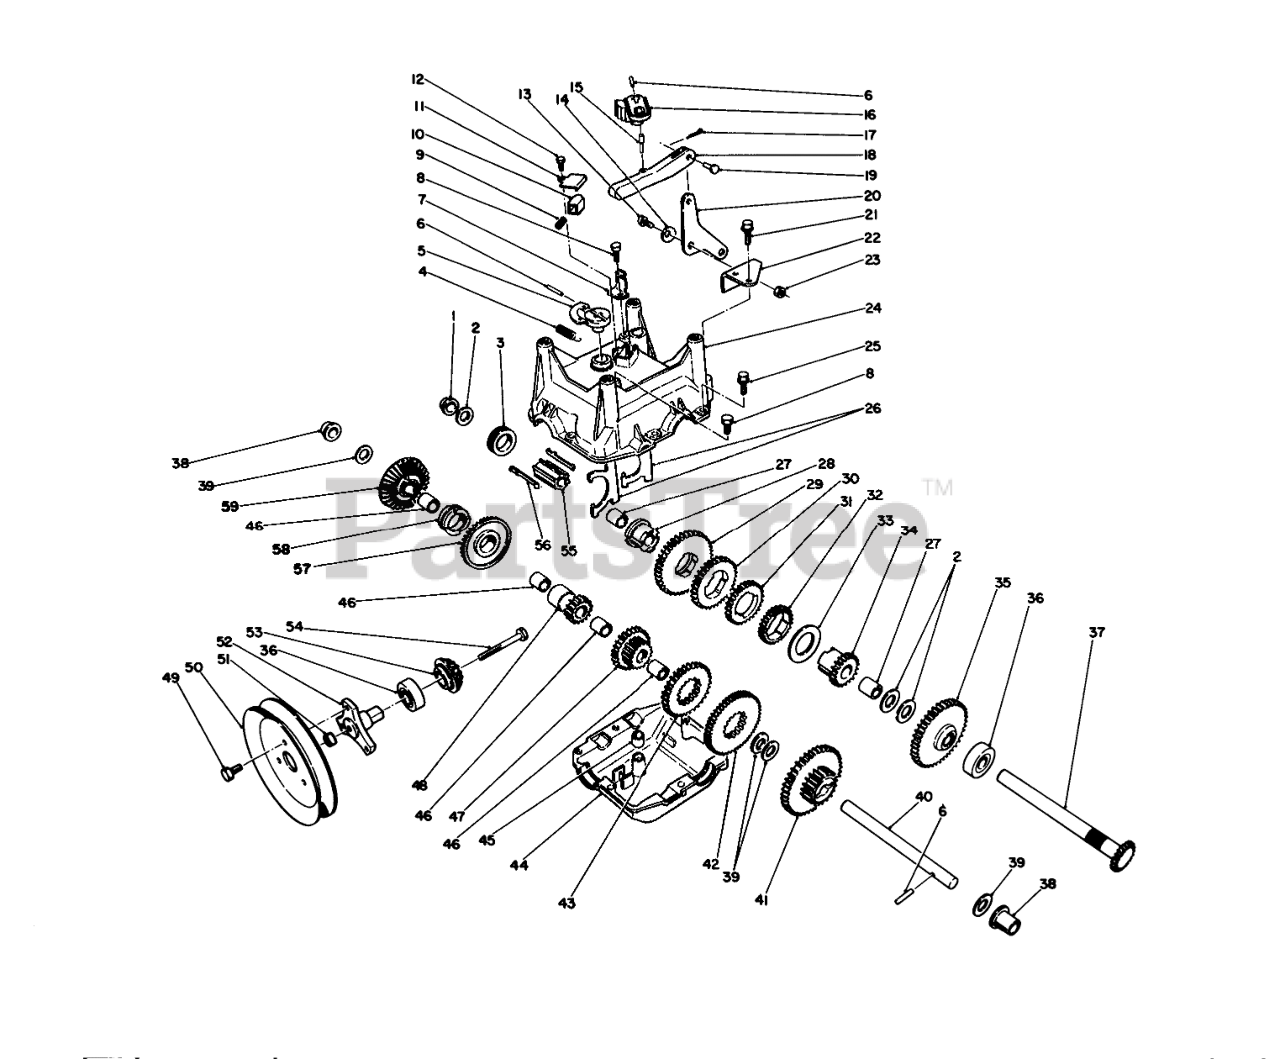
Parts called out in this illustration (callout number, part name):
1	BUSHING-FLANGE, OUTPUT
2	BEARING-THRUST
3	COLLAR-SHIFT
4	SPRING-EXTENSION
5	LEVER
6	PIN-SPRING
7	BRACKET-CABLE
8	SCREW-HWH
9	SPRING-DETENT
10	BUTTON-DETENT
11	COVER-DETENT
12	SCREW-HWH
13	SCREW-SHOULDER
14	WASHER-CURVED
15	PIN-LINK, GEAR SHIFT
16	LEVER-SHIFT, GEAR
17	PIN-COTTER
18	LINK-SHIFT, GEAR
19	PIN-CLEVIS
20	BELLCRANK
21	SCREW-HWH
22	BRACKET-BELLCRANK
24	GEARCASE-UPPER, CASING
25	SCREW-HWHTF
26	YOKE-SHIFT
27	BUSHING-OUTPUT
28	SLEEVE-GEAR
29	GEAR-45 T
30	GEAR-34 T
31	GEAR-27 T
32	GEAR-29 T
33	WASHER-THRUST
34	GEAR-SLEEVE, 19 T
35	GEAR-41 T
36	BEARING-BALL
37	SHAFT-OUTPUT
38	BUSHING-INTERMEDIATE
39	WASHER-THRUST
40	SHAFT-INTERMEDIATE
41	GEAR-19/41 T
42	GEAR-51 T
43	GEAR-33 T
44	GEARCASE-LOWER, CASING
45	BUSHING-YOKE
46	Bushing-Output
47	GEAR-26 T
48	GEAR-BEVEL, 15 T
49	SCREW
50	TRACTION-SHEAVE, HALF
51	NUT-HHF
52	HUB-PULLEY
53	PINION-BEVEL
54	SCREW-HH
55	SLEEVE-SHIFT
56	KEY-SHIFT
57	GEAR-BEVEL, 36 T
58	COLLAR-SHIFT
59	Gear-Bevel Reverse 36T (Incl. Ref. #46)
